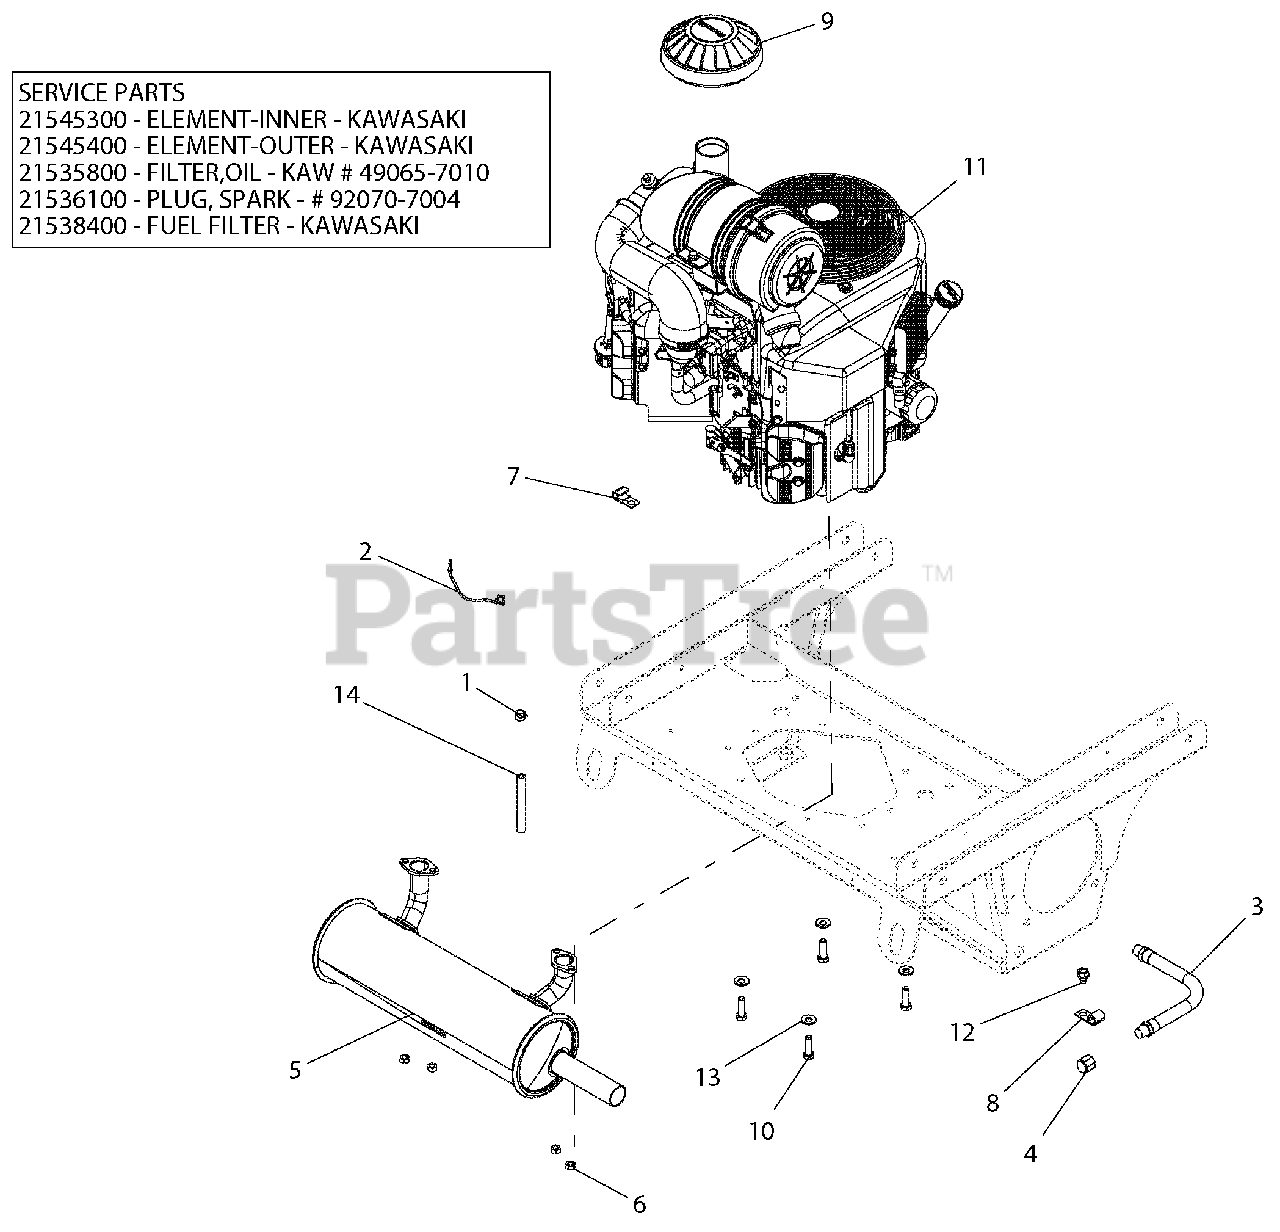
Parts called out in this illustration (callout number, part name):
1	CLAMP, FUEL LINE
2	LEAD - STARTER SOLENOID
3	HOSE, HYD .38-11-0K M6N0-M6NO
4	PIPE, CAP 3/8 NPT FEMALE
5	MUFFLER, 27-31 FX KAW
6	NUT-LK-TOP M8-1.25 YWZC
7	CLAMP, J
9	CAP, AIR CLEANER INTAKE (2")
10	BLT-HEX .38-16X1.25 GR5 YWZC NYTORQ
11	ENGINE, KAWASAKI FX751
12	SCR-TAP .38-16X.50 HWH TR YWZ
13	WSHR, 3/8" SPRING DISC
14	.25 LOW-PERM GAS HOSE 19.00" LG - RH TANK TO VALVE
